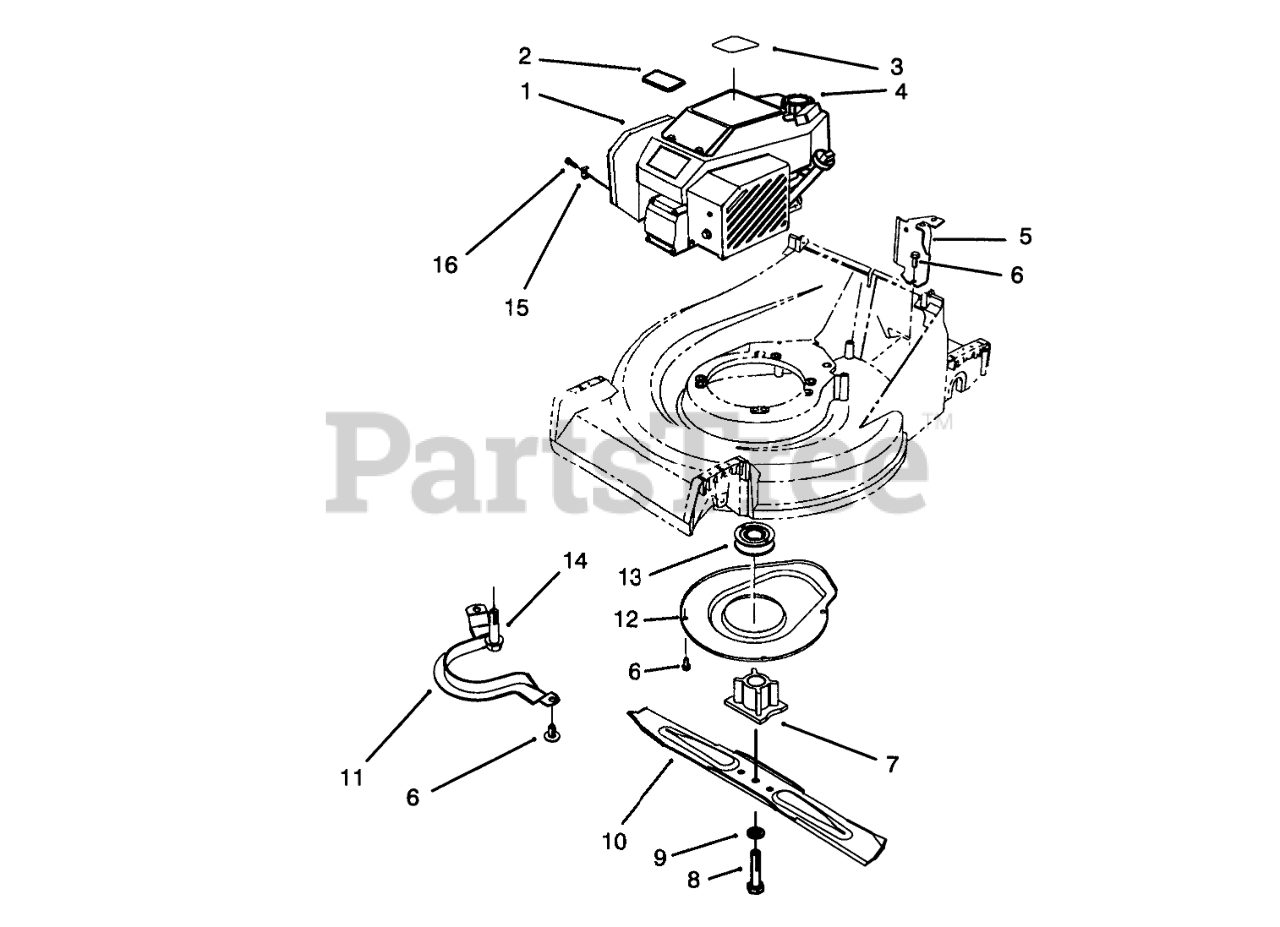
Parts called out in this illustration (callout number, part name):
1	ENG ASM-GTS 150 NC
2	PLATE-LOGO
3	DECAL - ENGINE
4	GAS CAP ASM
5	Bracket-Cable Support
6	SCREW-HWHTF
7	BLADE RETAINER
8	SCREW-BLADE
9	WASHER-LOCK
10	Key
11	Guide-Belt
12	Cover
13	PULLEY-DRIVE, ZONE START
14	SCREW-HWH
15	CLAMP-CASING
16	Screw-Clamp
